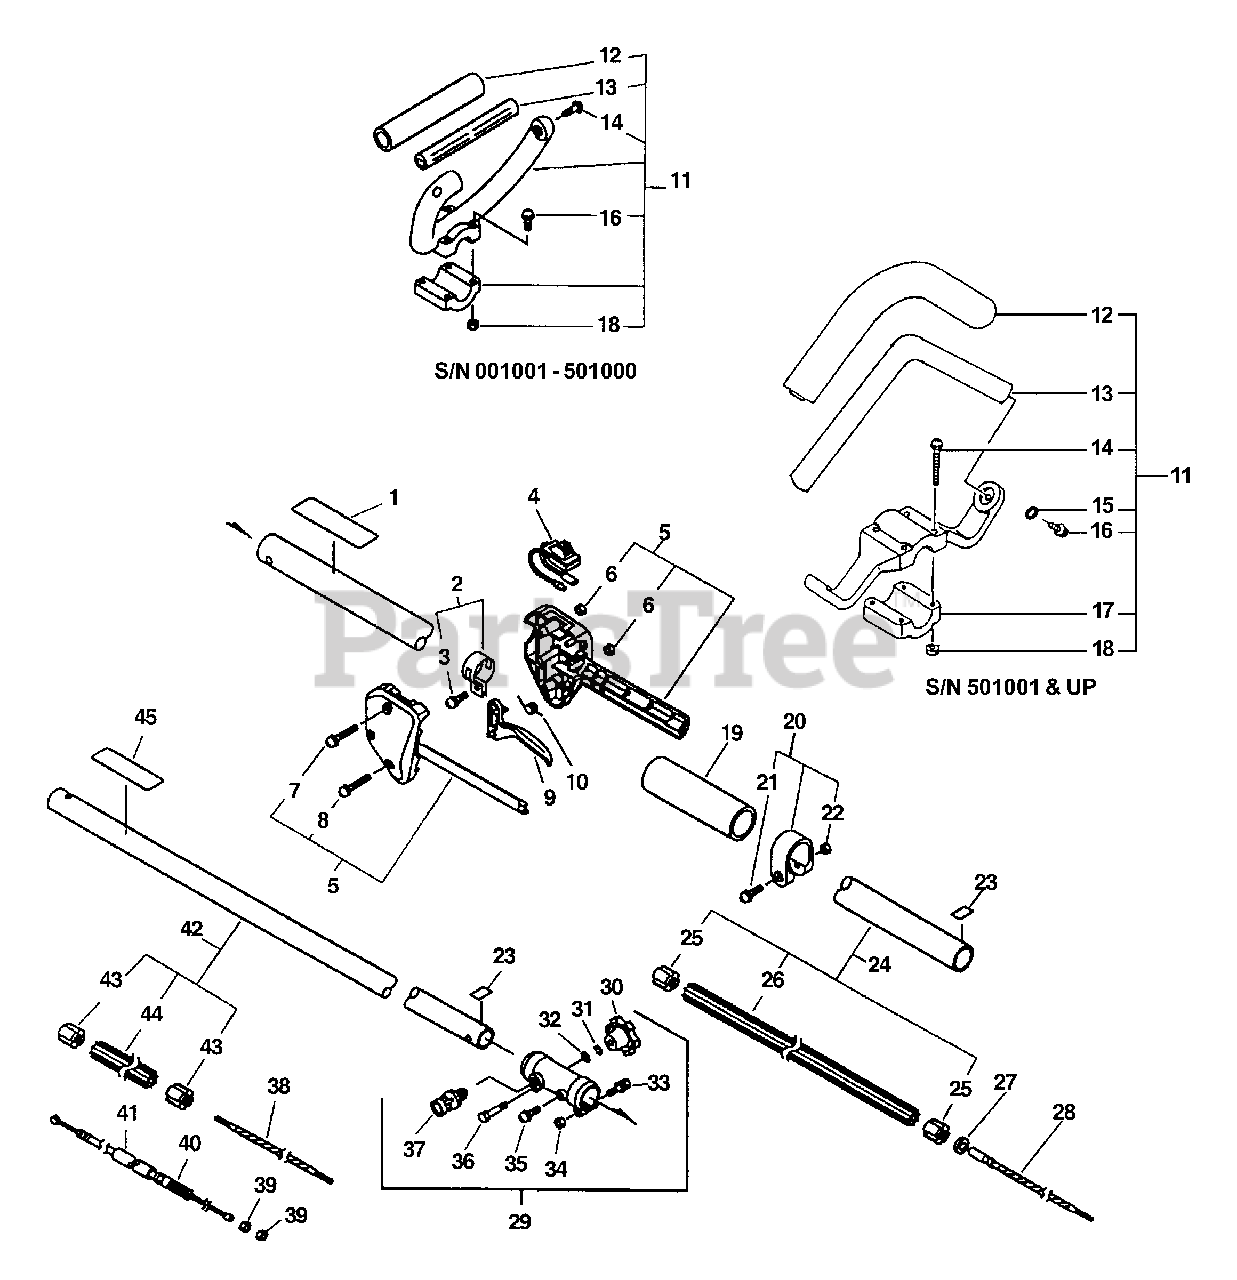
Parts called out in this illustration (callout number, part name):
1	LABEL, CAUTION
2	CLAMP KIT
3	SCREW 5×14
4	SWITCH ASSY, ON-OFF
5	HANDLE KIT, CONTROL
6	NUT M5
7	SCREW 5×35
8	SCREW 5×25
9	TRIGGER, THROTTLE
10	SPRING, TORSION
11	LOOP HANDLE ASSY
11	FRONT HANDLE ASSY
12	GRIP, HANDLE
13	HANDLE
13	HANDLE, SUPPORT
14	SCREW 5×30
14	SCREW 5×35
16	SCREW 5×35
16	SCREW 5
17	BRACKET, HANDLE - LOWER
18	NUT M5
19	GRIP, HANDLE
20	CLAMP KIT
21	SCREW 5×28
22	NUT M5
23	LABEL - ALIGNMENT
24	MAIN PIPE ASSY
26	LINER - FLEXIBLE
28	DRIVESHAFT - FLEXIBLE
29	COUPLER ASSY
30	KNOB, FASTENER
31	WASHER, SPRING 5
32	WASHER, FLAT 5.5×10×0.8
33	BOLT 5×30
34	NUT M5
35	SCREW 5×12
36	BOLT 5×35 SP
37	LATCH ASSY
38	DRIVESHAFT - FLEXIBLE
40	CABLE, THROTTLE
42	MAIN PIPE ASSY
44	LINER - FLEXIBLE
45	LABEL, CAUTION
